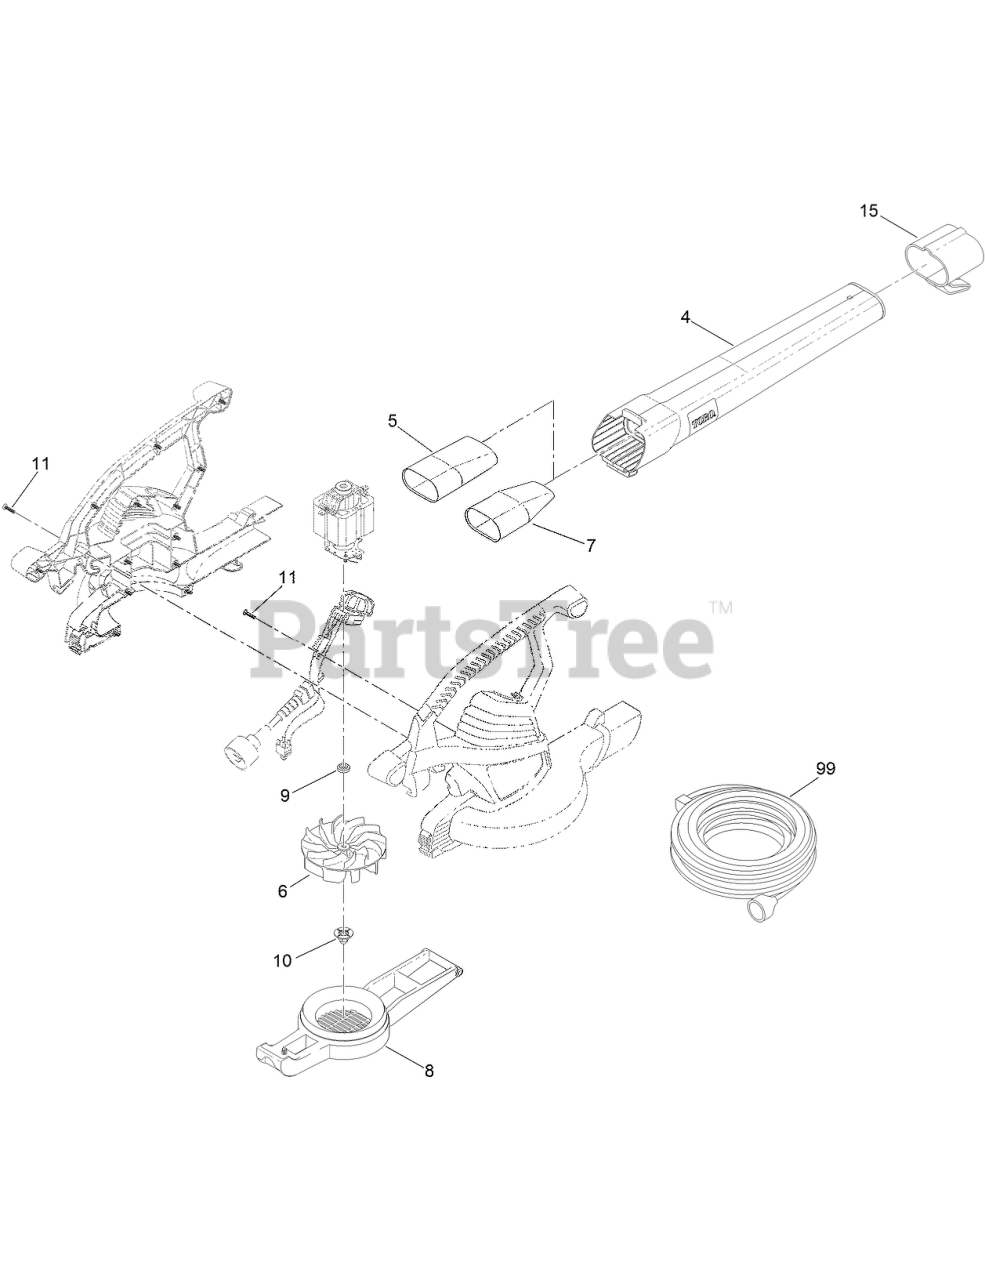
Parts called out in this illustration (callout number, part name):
4	TUBE-BLOWER
5	TUBE-INSERT
6	IMPELLER ASM
7	INSERT-TUBE, MPH
8	COVER-INLET
9	BUSHING-MOTOR
10	NUT-IMPELLER
11	SCREW-PPH
15	ADAPTER-WRAP, CORD
99	EXTENSION CABLE (12M)
